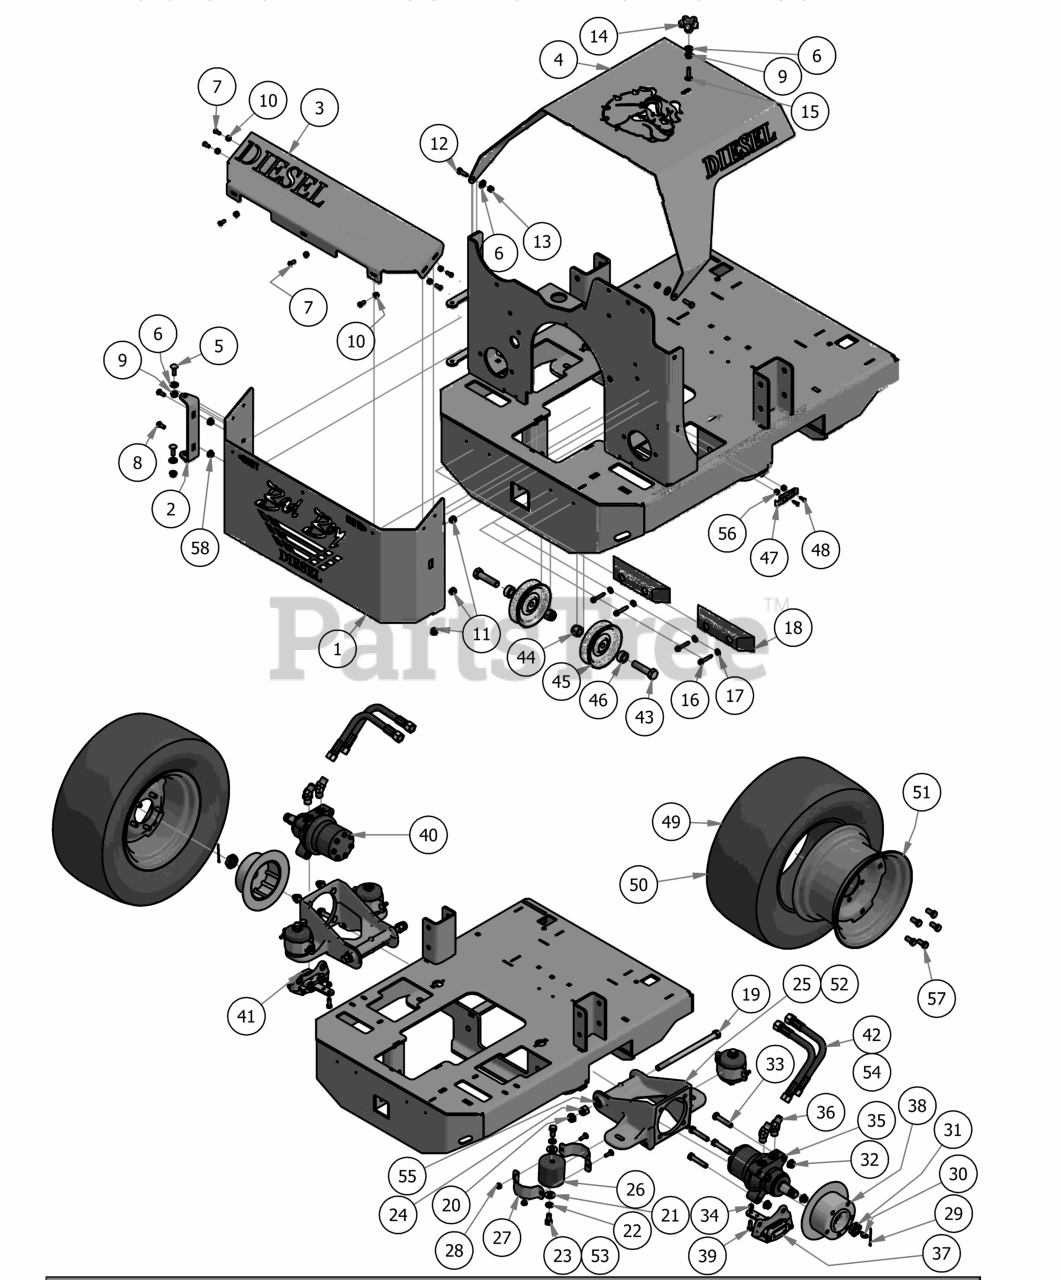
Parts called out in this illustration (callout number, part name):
1	Diesel Back Pump Cover 2008 Bottom
2	Back Cover Hinge Bracket
3	Diesel Back Pump Cover 2008 Top
4	Diesel Hood 4 Cyl
5	5/16" x 1" Carriage Bolt
6	.360 ID Plastic Washer
7	1/4" x 5/8" BS C/S 18-8 SS
8	5/16-18x3/4 carriage bolt
9	5/16" Flange Nut
10	1/4 Nylock Nut
11	5/8 Round Insert
12	5/16" x 1" Bolt
13	5/16-18 Nylock Insert Locknut
14	5/16" Knob
15	5/16" x 1 1/4" Carriage Bolt
16	1/4" x 1 1/2" Self Tapping Screw
17	1/4" Flat Washer
18	8" Rubber Bumper
19	5/8''x10'' Hex Bolt (Grade8)
20	5/8" Nylock (1/2 Jam)
21	1/2" Washer (Grade 8)
22	1/2" Lock Washer
23	1/2" x 1" Hex Bolt
24	5/8 Std NC Nylock Nut
25	60 Suspension kit Wheel Motor
26	Vibration Mount-Blue Dot
27	Isolator Band Clamp
28	5/16" Nylon Flange Nut
29	1/8x2-1/4 cotter pin Zinc
30	Woodruff Key
31	1" Castle Nut for Wheel Motor
32	1/2" Flange Nut
33	1/2" x 2 1/2" Hex Bolt
34	5/16-18 Nylock Insert Locknut
35	18cc Parker Wheel Motor- Right
36	45 Degree Wheel Motor Fitting -6802-10-10
37	XP/AOS Right Brake Caliper
38	Brake Disk
39	3/8" x 1" Hex Bolt
40	18cc Parker Wheel Motor- Left
41	XP/AOS Left Brake Caliper
42	26" Hose Assembly with Adaptors
43	5/8" x 2 1/2" Grade 5 Hex Bolt (Coarse)
44	5/8 Std NC Nylock Nut
45	5 V Idler Pulley - BCVI- 81
46	5/8" x 1/" Collar W/One Set Screw
47	Steel Pump Cover Latch
48	10-24 X 5/8 BS Button Head Bolt
49	26 x 12.00 - 12 Tire and Orange Wheel Assembly
50	26 x 12.00 - 12 Tire
51	12 x 10.5 Wheel AOS Rear
52	72 Suspension Kit Wheel Motor
53	1/2-13 1-1/4 Hex bolt Only On 60" Suspension Kit Wheel Motor
54	26" Hose Only
55	Brass Bushing
56	10-24 Nylock Locknut
57	1/2" x 1" Hex Bolt
58	5/16" Nylon Flange Nut
